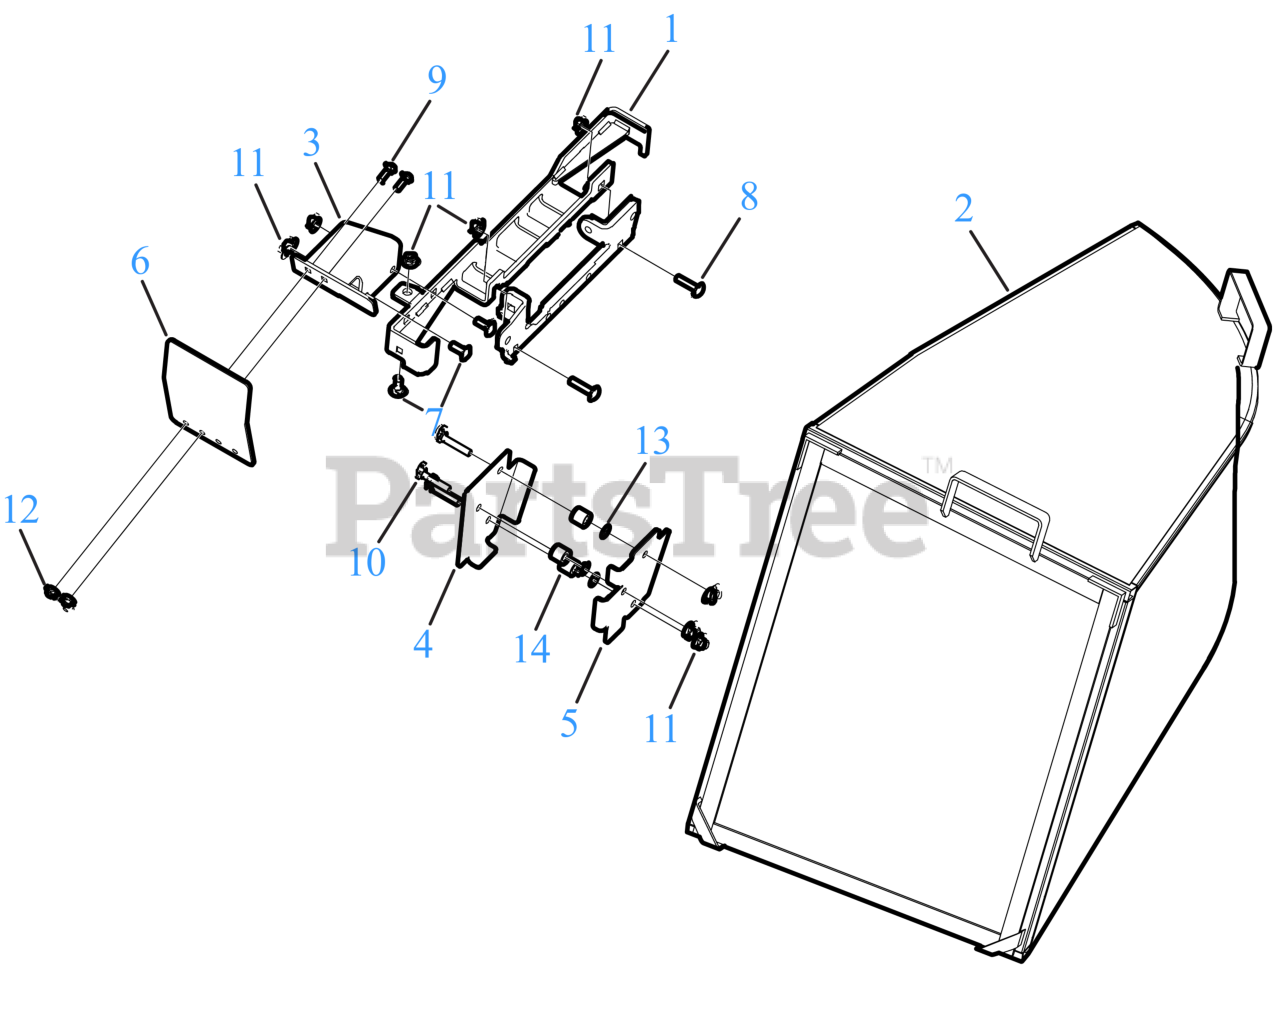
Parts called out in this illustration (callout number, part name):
1	MOUNT BRACKET
2	GRASSBAG
3	DEFLECTOR CHUTE BRACKET
4	OUTER BAG BAFFLE
5	INNER BAG BAFFLE
6	DEFLECTOR BRACKET
7	CARRIAGE BOLT 5/16-18 x .75
8	CARRIAGE BOLT 5/16-18 x 1.25
9	SCREW 1/4-20 x .75 GR5
10	SCREW 5/16-18 x 1.5 LG
11	FLANGE LOCK NUT 5/16-18
12	FLANGE LOCK NUT
14	SPACER .34 x .75 x .63 LG
